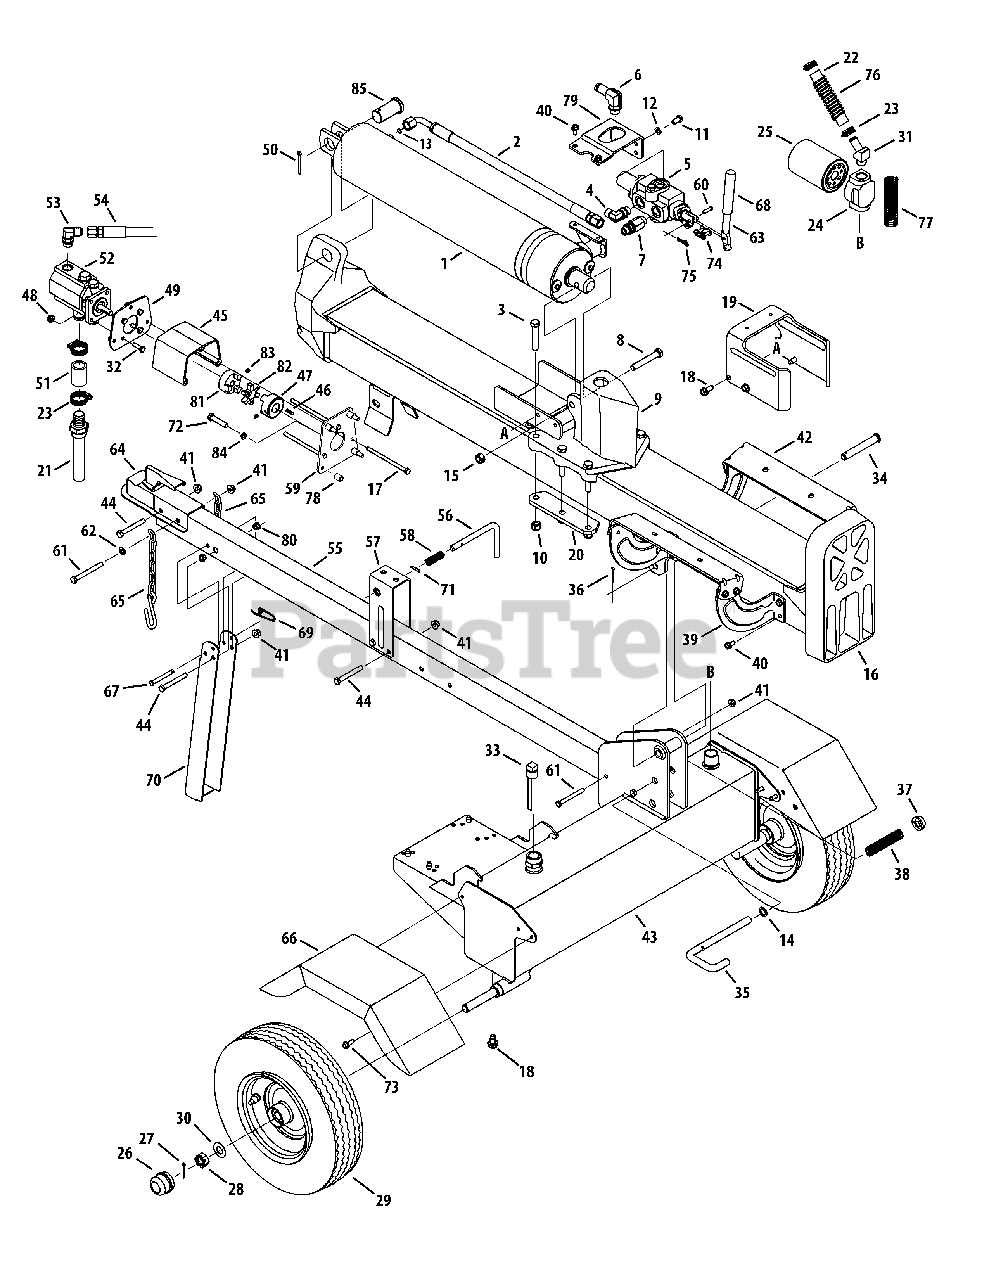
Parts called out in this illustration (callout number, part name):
1	Hydraulic Cylinder
2	Hydraulic Tube
3	Hex Cap Screw, 1/2-20 x 2.75
4	90 Degree Solid Adapter
5	Control Valve
6	Return Elbow
7	Nipple Pipe, 1/2-14
8	Hex Cap Screw, 1/2-13 x 3.25
9	Wedge Assembly
10	Hex Lock Nut, 1/2-20
11	Hex Cap Screw, 3/8-16 x .75
12	Lock Washer, 3/8
13	O-Ring, .489 ID x .070 Dia.
14	Flat Washer, .635 x.93 x.06
15	Hex Lock Nut, 1/2-13
16	Beam Assembly
17	Hex Screw, 5/16-18 x 4.75
18	Self Tapping Screw, 3/8-16 x 1.0
19	Dislodger Bracket
21	Inlet Filter
22	Return Hose, 3/4 x 44
23	Hose Clamp, 5/8
24	Filter Housing
25	Oil Filter
27	Cotter Pin
28	Slotted Nut, 3/4-16
29	Complete Wheel Assembly
29	Dust Seal
29	Roller Bearing
30	Flat Washer, .760 x 1.500
31	Hydraulic Fitting, 1 1/16 Orb x .75
32	Hex Screw, 5/16-18 x 1.00
33	Vented Dipstick
34	Clevis Pin
36	Cotter Pin
38	Compression Spring
39	Log Tray Bracket
40	Hex Washer Screw, 5/16-18 x .750
41	Flange Lock Nut, 3/8-16
43	Frame Assembly
44	Hex Bolt, 3/8-16 x 3
45	Coupling Shield
46	Square Key, 3/16 x .75
47	Coupling, .875
48	Flange Lock Nut, 5/16-18
49	Rear Coupling Support Bracket
50	Cotter Pin, 3/16 x 2
53	Hydraulic Fitting, 7/8 Orb x .8125
54	High Pressure Hydraulic Hose
55	Tongue Assembly
56	Latch Rod
58	Compression Spring
59	Front Coupling Support Bracket
60	Clevis Pin
61	Hex Cap Screw, 3/8-16 x 3.50
62	Flat Washer, .375 x.738 x.063
63	Hydraulic Valve Control
64	Hitch Coupling Assembly
67	Clevis Pin
69	Spring Pin
71	Spiral Pin
72	Hex Cap Screw, 5/16-24 x .75
73	Self-Tapping Screw, 5/16-18 x 1.00
74	Valve Handle Link
75	Cotter Pin, Bow Tie
76	Hose Guard, 48"
77	Hose Guard, 44"
78	Spacer, .385 x .623 x .75 LG
79	Outer Valve Bracket
80	Plastic Bushing, .380 ID
81	Coupling, .500
82	Spider Bushing
83	Set Screws
84	Lock Washer, 5/16
85	Clevis Pin, 1.25 x 2.50
